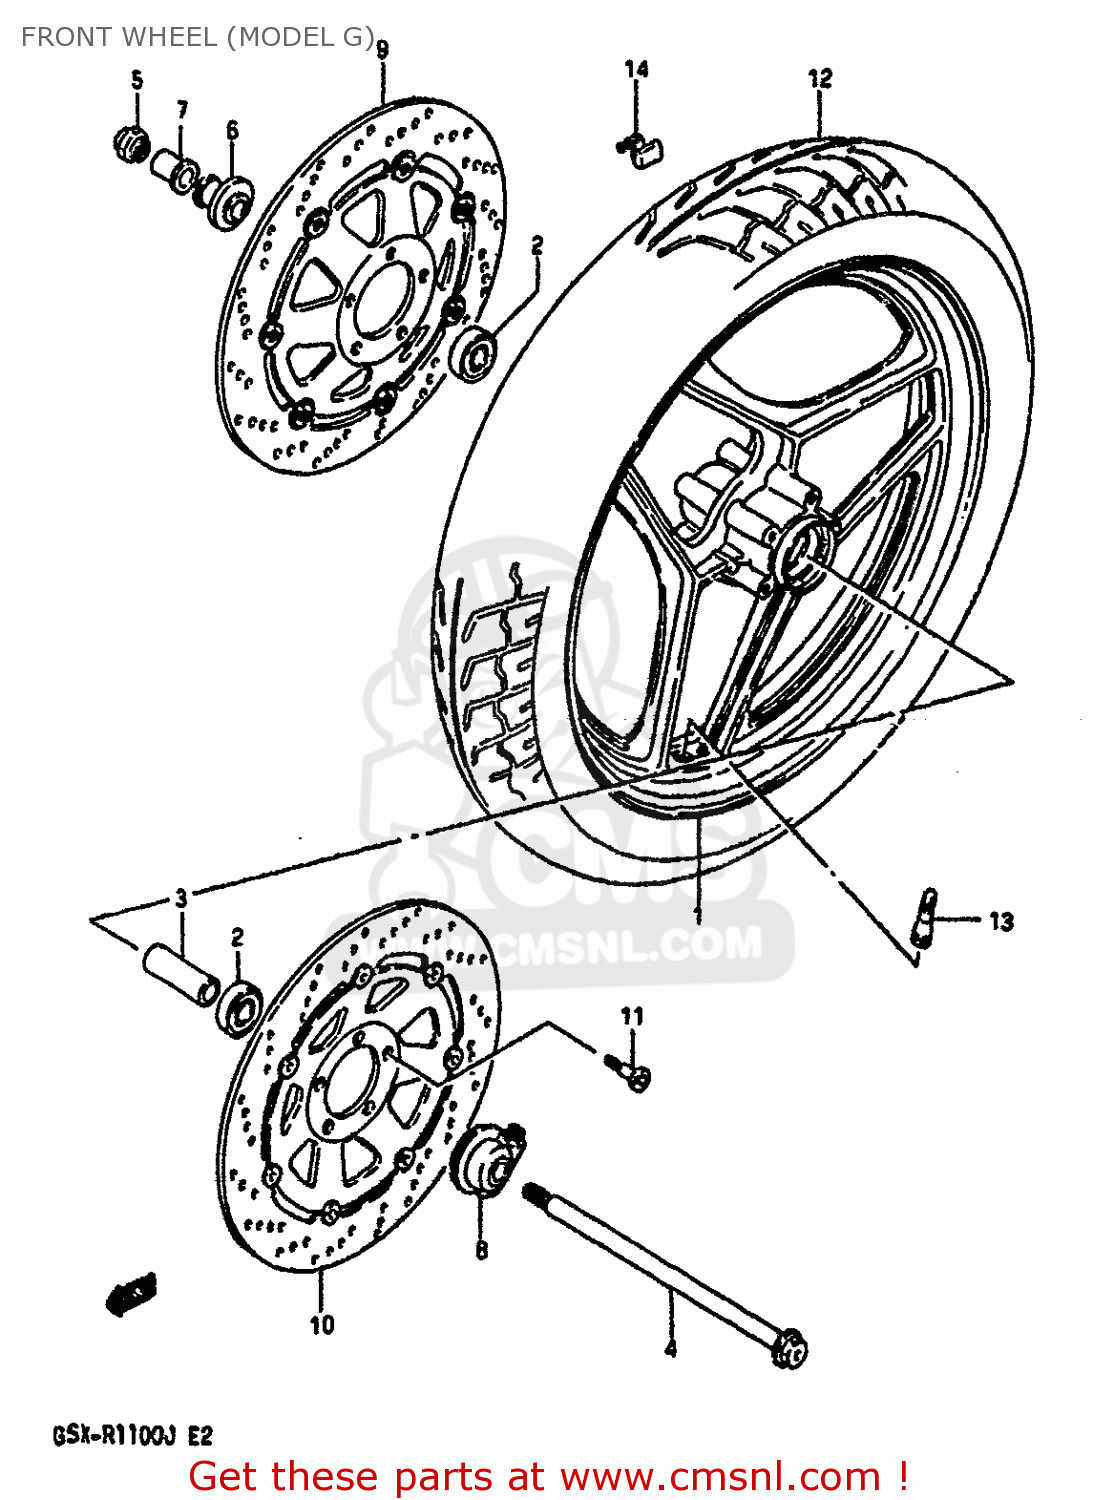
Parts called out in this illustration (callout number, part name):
1	WHEEL,FRONT (MT2.75X18)
2	BEARING
3	SPACER(15.3X21.7X77)
4	AXLE, FRONT
5	NUT
6	SPACER,FR HUB BEARING,R
7	SPACER
8	BOX ASSEMBLY,SPEEDOMETER GEAR
9	DISC,BRAKE
10	DISC,BRAKE
11	BOLT
12	TIRE,TUBELESS 110/80V
13	VALVE,TIRE
14	BALANCER,WHEEL
